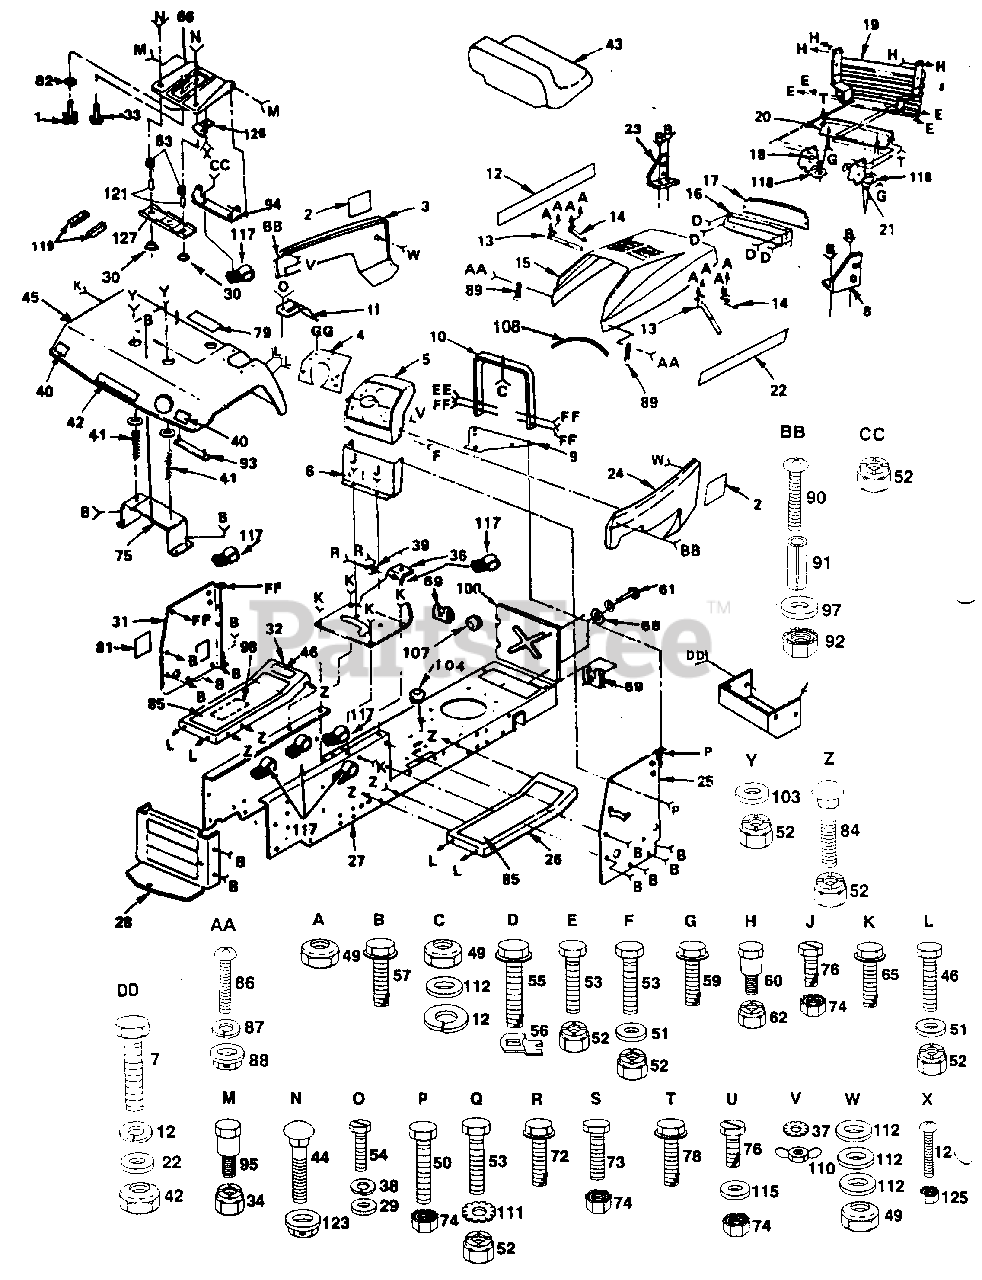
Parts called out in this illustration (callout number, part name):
1	Adjustment Knob (AYP part number)
2	Deflector, Heat (AYP part number)
3	Panel, Side, L.H. (AYP part number)
4	Dash, Plate (AYP part number)
5	Dashboard (AYP part number)
6	Dash Assembly, Lower (AYP part number)
7	Bolt, Hex Head 1/4-20 UNC x 3/4 (AYP part number)
8	Bracket Assembly, R.H. (AYP part number)
9	Plate, Support, Battery (AYP part number)
10	Support, Assembly, Dash (AYP part number)
11	Console, Shifter
12	Washer, Lock Heavy Helical 1/4 (AYP part number)
13	Strap, Assembly, Hinge, Rear (AYP part number)
14	Strap, Assembly, Hinge, Front (AYP part number)
15	Hood (AYP part number)
16	Bezel, Assembly
17	Lens (AYP part number)
18	Support, Grill, L.H. (AYP part number)
19	Grill, Assembly (AYP part number)
20	Strap, Grill (AYP part number)
21	Support, Grill, R.H. (AYP part number)
22	Washer 9/32 x 7/8 x 16 Gauge (AYP part number)
23	Bracket Assembly, L.H. (AYP part number)
24	Panel, Side, R.H. (AYP part number)
25	Panel, Dash, R.H. (AYP part number)
26	Footrest, R.H. (AYP part number)
27	Chassis (AYP part number)
28	Drawbar (AYP part number)
29	Washer 3/16 x 7/16 x 18 Gauge (AYP part number)
30	Bushing, Snap (AYP part number)
31	Panel, Dash, L.H. (AYP part number)
32	Footrest, L.H. (AYP part number)
33	Bolt, Shoulder 5/16-18 x.62 (AYP part number)
34	Nut, Crownlock 5/16-18
35	Cap, Spring (AYP part number)
36	Saddle (AYP part number)
37	Washer, Lock, Int./Ext. Tooth 1/4 (AYP part number)
38	Washer, Lock #8 (AYP part number)
39	Bushing, Steering (AYP part number)
41	Spring, Compression (AYP part number)
42	Nut, Self-Retaining 1/4-20 (AYP part number)
43	Seat (AYP part number)
44	Bolt, Carriage 1/4-20 x 1-1/4 (AYP part number)
46	Bolt, Fin, Hex 3/8-16 x 3/4 (AYP part number)
49	Nut, Hex 1/4-20 (AYP part number)
50	Bolt, Hex 3/8-16 x 1-1/4 (AYP part number)
51	Washer 13/32 x 13/16 x 12 Gauge (AYP part number)
52	Nut, Crownlock 3/8-16
53	Bolt, Hex 3/8-16 x 1 (AYP part number)
54	Screw #8-3/8 (AYP part number)
55	Screw, Hex Washer Head Tapping #10-16 x 5/8 (AYP part number)
56	"J" Fastener (AYP part number)
57	Screw, Hex Washer Head, Threaded, Rolling 3/8-16 x 3/4 Type TT (AYP part number)
59	Screw, Hex Washer Head, Threaded, Rolling 5/16-18 x 3/4 Type TT
60	Bolt, Shoulder 1/4-20 (AYP part number)
61	Stud 1/4 Turn
62	Nut, Crownlock 1/4-20 (AYP part number)
63	Spring, Compression (AYP part number)
65	Screw, Hex Washer Head, Thread Forming 3/8 -16 x 1/2 Type TT (AYP part number)
66	Pan, Seat (AYP part number)
68	Retainer 1/4 Turn (AYP part number)
69	Receptacle 1/4 Turn (AYP part number)
70	Washer 9/32 x 5/8 x 16 (AYP part number)
72	Screw, Hex Head #10-16 x 1/2 Type B (AYP part number)
73	Bolt, Hex 5/16-18 x 3/4 (AYP part number)
74	Nut, Keps 5/16-18 (AYP part number)
75	Bracket Assembly, Fender (AYP part number)
76	Screw, Machine 5/16-18 x 3/4 (AYP part number)
78	Screw, Hex Washer Head 1/4-20 x 3/4 (AYP part number)
81	Cover, Access (AYP part number)
82	Washer 17/32 x 1-3/16 x 12 Gauge (AYP part number)
84	Bolt, Carriage 3/8-16 x 3/4 (AYP part number)
85	Pad, Footrest (AYP part number)
86	Screw, Cross Recess Pan Head, Machine #1 0-24 x 1/2 (AYP part number)
87	Washer, Lock #10 (AYP part number)
88	Nut, Weld (AYP part number)
89	Latch, Hood (AYP part number)
90	Screw, Machine, Cross Recess #10-24 x 1-1/4 (AYP part number)
91	Spacer, Split #10 x 3/4 (AYP part number)
92	Nut, Keps #10-24 (AYP part number)
93	Strap Assembly, Fender (AYP part number)
94	Bracket, Pivot, Seat (AYP part number)
95	Bolt, Shoulder 5/16-18 (AYP part number)
97	Washer 7/32 x 1/2 x 18 Gauge (AYP part number)
100	Shield, Heat (AYP part number)
103	Washer 13/32 x 1 x 14 Gauge (AYP part number)
104	Grommet (AYP part number)
107	Grommet, Split (AYP part number)
108	Foam, Strip (AYP part number)
110	Wing Nut 1/4-20 (AYP part number)
111	Washer, Lock, External Tooth 3/8 (AYP part number)
112	Washer 9/32 x 3/4 x 16 Gauge (AYP part number)
113	Nut, Hex 1/4-20 (AYP part number)
115	Washer 11/32 x 3/4 x 12 Gauge (AYP part number)
117	Clip, Insulated (AYP part number)
118	Washer 11/32 x 3/4 x 12 Gauge (AYP part number)
119	Foam, Strip (AYP part number)
121	Spacer, Split 0.28 x 0.88 (AYP part number)
123	Locknut, Hex, Large, Flanged 1/4-20 UNC (AYP part number)
124	Screw, Sltd. Pan Head #10-32 x 1/2 (AYP part number)
125	Nut, Keps #10-32 UNC (AYP part number)
126	Clip, Insulated (AYP part number)
127	Bracket, Switch Mount (AYP part number)
